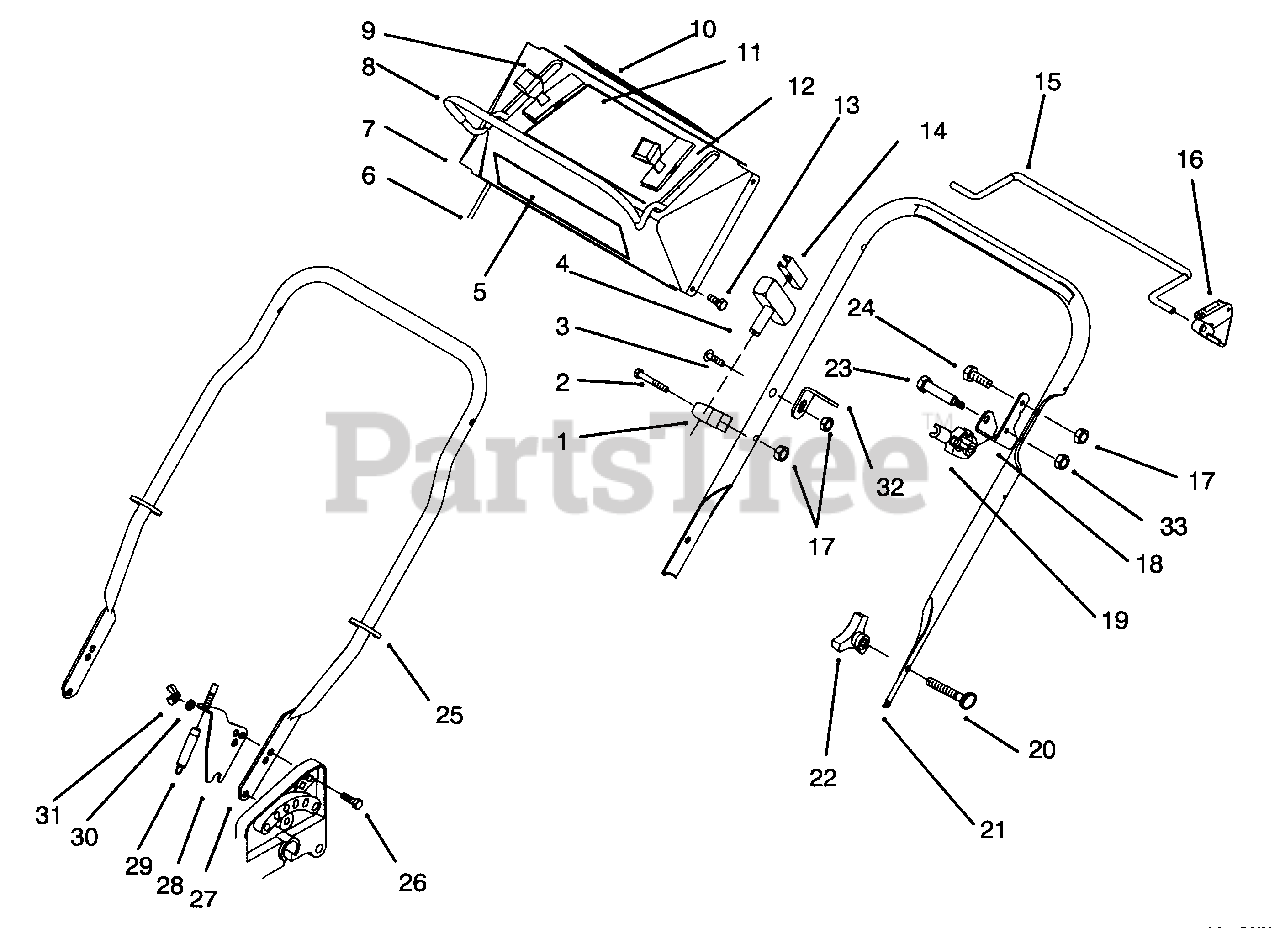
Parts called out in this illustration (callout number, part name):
1	Guide-Rope
4	Handle-Rope
5	Decal-Control Panel
6	Cable-Brake
7	Panel-Control (Self Propelled Incl. Ref.#10 & 11)
8	Bail-Brake
8	Decal-Warning (French/English)
8	Decal-Control Panel Hand Push French/English)
8	Decal-Control Panel (Hand Push French/English)
9	Control Ground Speed (Self Propelled)
10	Decal-Warning (English)
11	Decal-Control Panel (Self Propelled English)
12	Control-Throttle
14	Insert-Handle
15	Bail-Control (Self Prop.)
16	Stop-Pivot (Self Prop.)
18	Bracket-Cam
19	Brake-BBC Cam
20	Screw-Handle
21	Handle-Upper
22	Knob-Handle
23	Bolt-Shoulder
24	Screw-Hex. Hd.
25	Tie-Cable
26	Bolt-Carriage
27	Handle-Lower
28	Bracket-Traction Cable (Self Propelled)
29	Cable-Traction (Self Propelled)
32	Bracket-Cable
